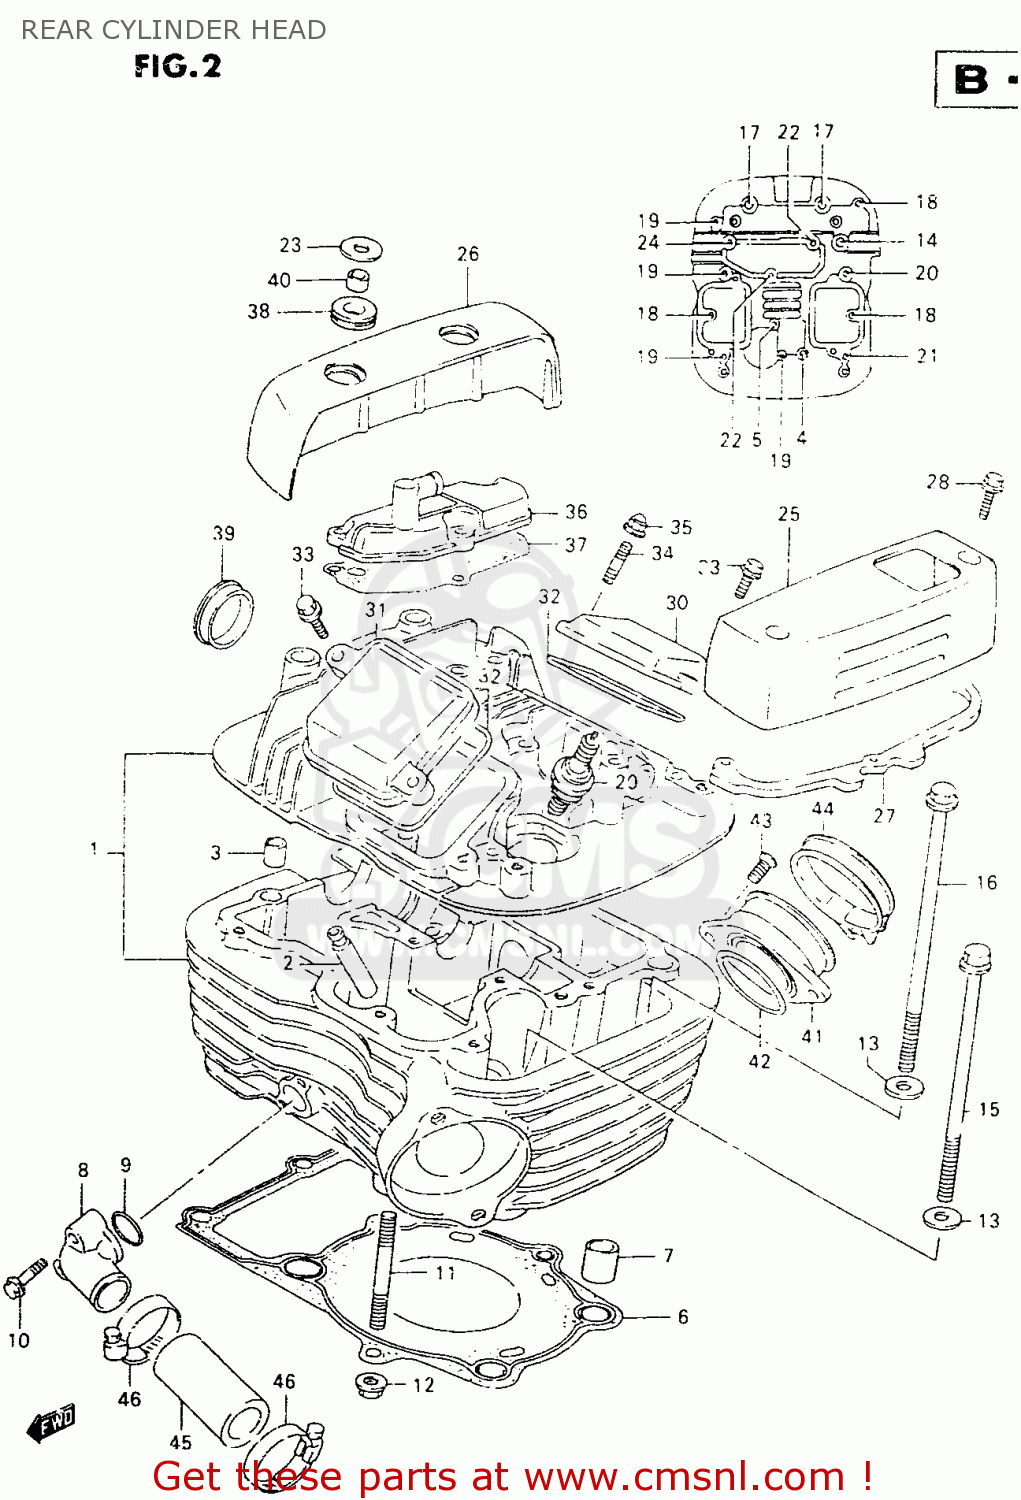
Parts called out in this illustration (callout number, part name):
1	HEAD ASSY,CYLINDER RR
2	GUIDE,VALVE
3	PIN(8.4X11X14)
4	BOLT(6X50)
5	BOLT(6X55)
6	GASKET,CYLINDER HEAD RR (NAS)
7	PIN
8	UNION,CYLINDER HEAD WATER
9	O RING(D:2.4,ID:17.8)
10	SCREW
11	BOLT,STUD
12	NUT
13	WASHER (10.5X22X2.3)
14	BOLT(8X140)
15	BOLT(10X155)
16	BOLT(10X165)
17	BOLT(8X245)
18	BOLT
19	BOLT
20	BOLT
21	BOLT
22	BOLT(6X55)
23	WASHER(8.5X24X1.6)
24	BOLT
25	CAP,CYLINDER HEAD COVER,R-L
26	CAP,CYL HEAD COVER,FL & RR
27	CUSHION,RR,L CAP
28	BOLT(6X35)
29	PLUG,SPARK(DPR8EA-9)
30	CAP,INSPECTION INTAKE
31	CAP,INSPECTION EXHAUST
32	GASKET,INSPECTION CAP (NAS)
33	BOLT
34	STUD 6X16
35	NUT
36	COVER,BREATHER
37	GASKET,BREATHER COVER (NAS)
38	CUSHION
39	PLUG(OD:30)
40	BUSH
41	PIPE,INTAKE,REAR
42	O-RING (D:2.4 ID:39.7)
43	SCREW
44	CLAMP
45	HOSE,CYLINDER HEAD JOINT
46	CLAMP
